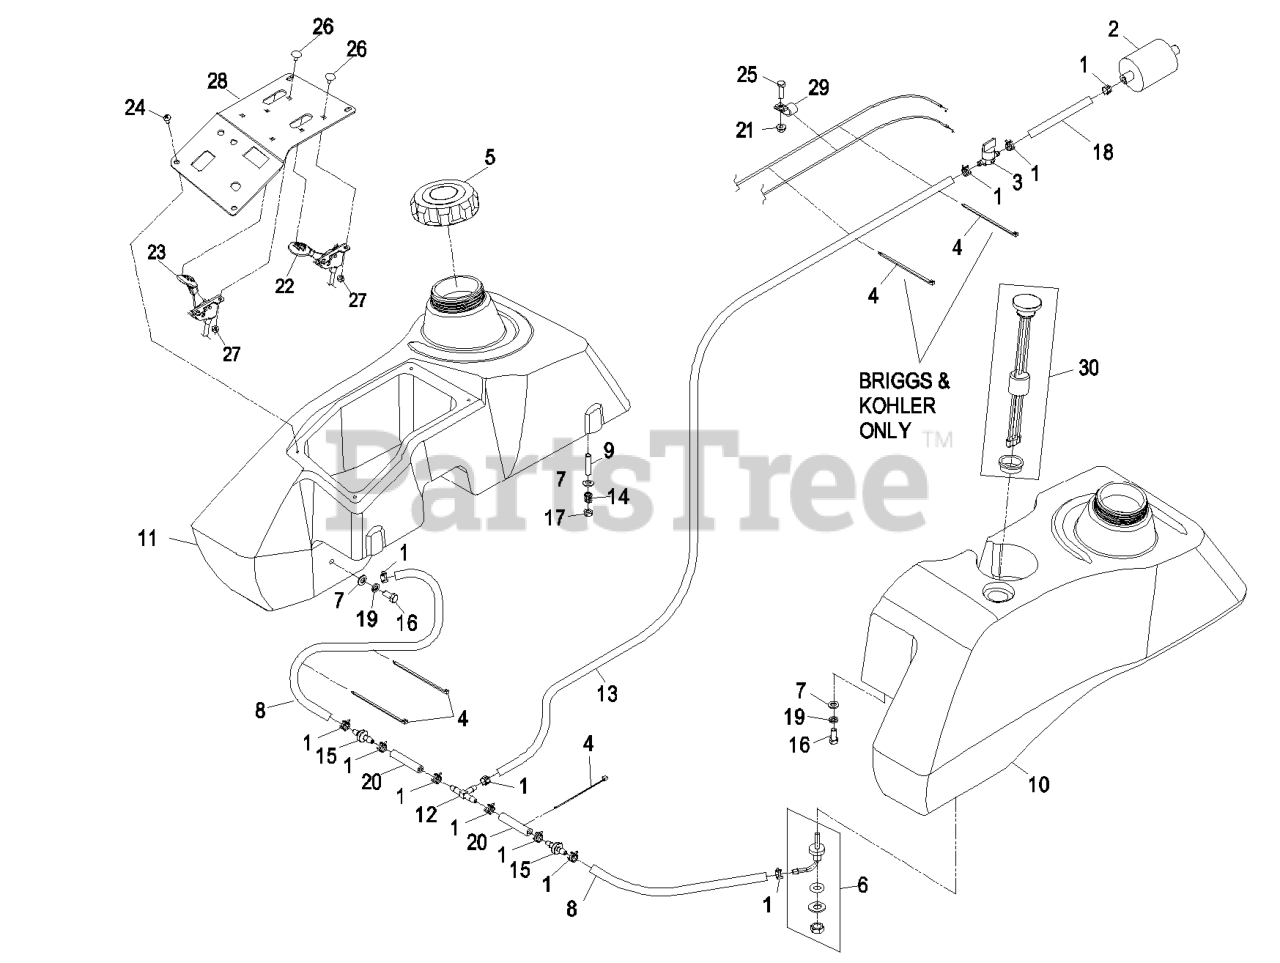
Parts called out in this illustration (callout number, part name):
2	Kohler Part No 2405010 Fuel Filter
3	VALVE-FUEL
4	TIE-PLASTIC
5	CAP-FUEL, GAS
6	FITTING-FUEL, BULKHEAD
7	WASHER-PLAIN
8	HOSE-FUEL
9	STUD
10	ASM,FUEL TANK LH
12	FITTING-TEE, BARBED
13	HOSE-FUEL
14	SPRING-TANK, FUEL
15	VALVE-CHECK, FUEL
16	SCREW-HH
17	NUT-LOCK, NI
18	HOSE-FUEL
19	WASHER-LOCK
20	HOSE-FUEL
22	CONTROL-THROTTLE
23	CONTROL,CHOKE
24	SCREW-PPH
25	SCREW-HH
26	BOLT-CARR
27	NUT-LOCK, NI
28	PANEL,CONTROL W/DECALS
29	CLIP-LOOM
30	Kit, Gauge Fuel
